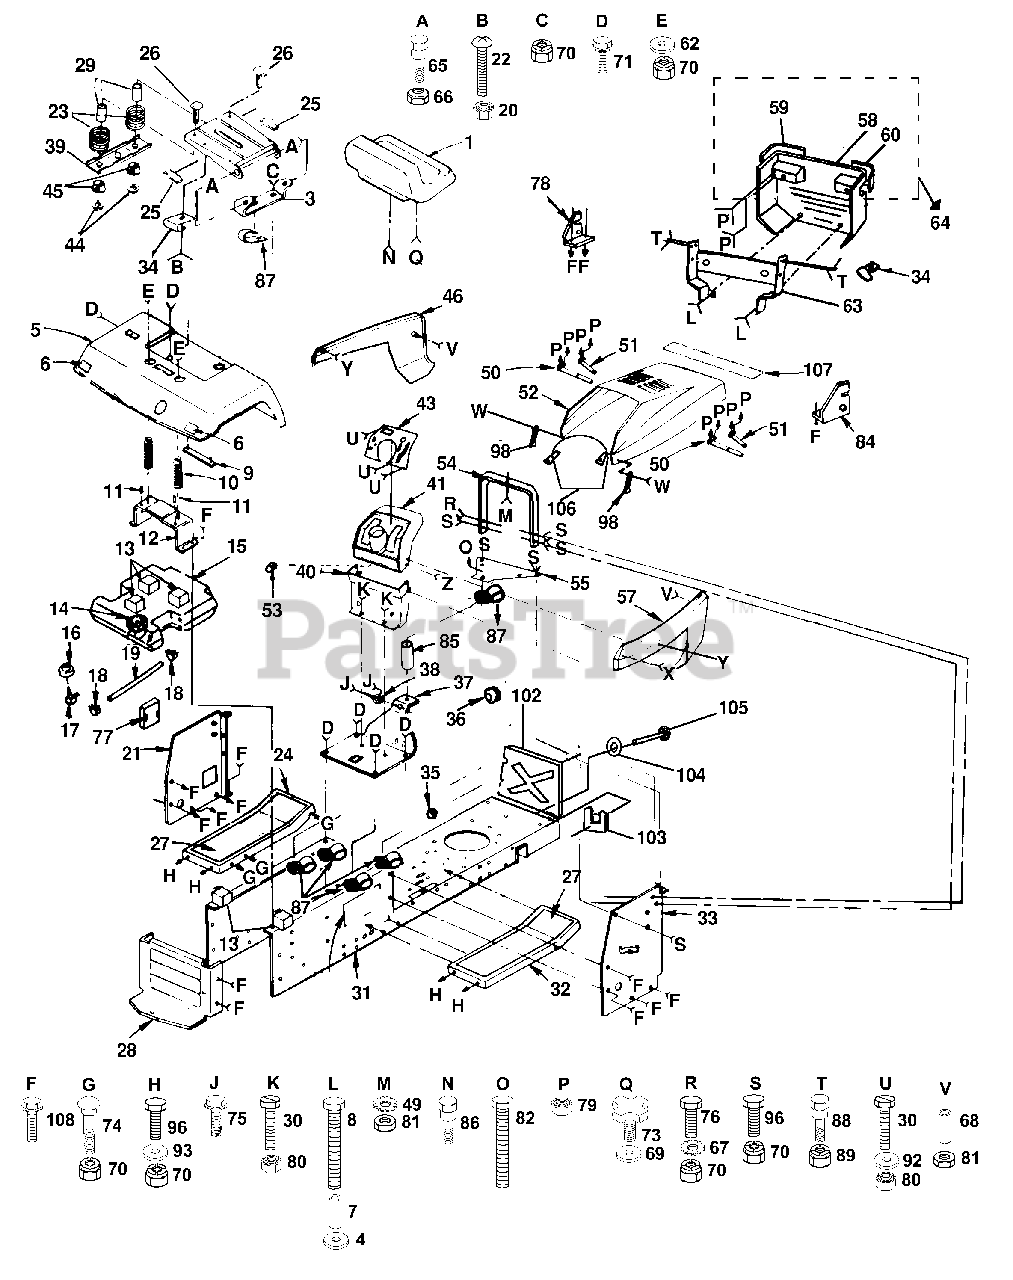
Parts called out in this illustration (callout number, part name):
1	Seat
3	Bracket, Pivot, Seat
4	Washer 9/32 x 3/4 x 16 Ga.
5	Fender
6	Reflector, Taillight
8	Bolt, Fin, Hex 1/4-20 x 2-1/2
9	Strap, Fender
10	Spring, Compression, Seat
12	Bracket, Fender
13	Pad, Spacer
15	Tank, Fuel
16	Bushing
17	Stem, Tank, Fuel
18	Clamp, Hose
19	Line, Fuel
20	Nut, Keps #10
21	Panel, Dash, L.H.
22	Screw, Pan Hd. #10-32
23	Spring, Compression
24	Footrest, L.H.
25	Foam, Strip
26	Bolt, Carriage 1/4-20 x 1-1/4
27	Pad, Footrest
28	Drawbar
29	Spacer, Split
30	Screw, Mach. Cr. Thd. 5/16-18 x 3/4
32	Footrest, R.H.
33	Panel, Dash, R.H.
34	Clip, Insulated
35	Grommet, Split
37	Saddle
38	Bushing, Steering
39	Bracket, Switch Mount
40	Assembly, Dash, Lower
41	Dash
42	Nut, Weld
43	Plate, Dash
44	Locknut, Flange Hex, Large
45	Bushing, Snap
46	Panel, Side, L.H.
49	Washer, Lock, Tooth External 1/4
50	Assembly, Strap Hinge, Rear
51	Assembly, Strap Hinge, Front
52	Hood
53	Plug, Button
54	Support, Dash
55	Plate, Support, Battery
57	Panel, Side, R.H.
58	Grill
59	Lens, L.H.
60	Lens, R.H.
62	Washer 13/32 x 1 x 14 Gauge
63	Support, Grill, Assembly
64	Assembly, Grill
65	Bolt, Shoulder 5/16-18
66	Locknut 5/16-18
67	Washer, Lock Tooth External 3/8
69	Washer 17/32 x 1-3/16 x 12 Gauge
70	Nut, Crownlock 3/8-16
71	Screw, Hex Washer Thread Rolling 3/8-16 x 1/2
73	Knob, 1/2" Seat
74	Bolt, Carriage 3/8-16 x 3/4
75	Screw, Hex Self Tapping #10-16 x 1/2
76	Bolt, Hex 3/8-16 x 1
77	Cover, Access
78	Bracket Assembly, L.H.
79	Nut, Keps, Hex 1/4-20 UNC
80	Nut, Keps, 5/16-18 UNC
81	Nut, Fin, Hex 1/4-20 UNC
82	Bolt, Hex 5/16-18 x 2
84	Bracket, Assembly R.H.
86	Bolt, Shoulder 5/16-18 x .62
87	Clip
88	Bolt, Shoulder 1/4-20
89	Nut, Crownlock 1/4-20
92	Washer 11/32 x 11/16 x 16 Gauge
93	Washer 13/32 x 13/16 x 12 Gauge
96	Bolt, Hex 3/8-16 x 3/4
98	Latch, Hood
102	Shield, Heat
103	Receptacle, 1/4 Turn
104	Retainer, 1/4 Turn
105	Stud, 1/4 Turn
106	Baffle, Vertical
107	Foam, Strip 18"
108	Screw, Hex Washer, Thread Rolling 3/8-16 x 3/4
